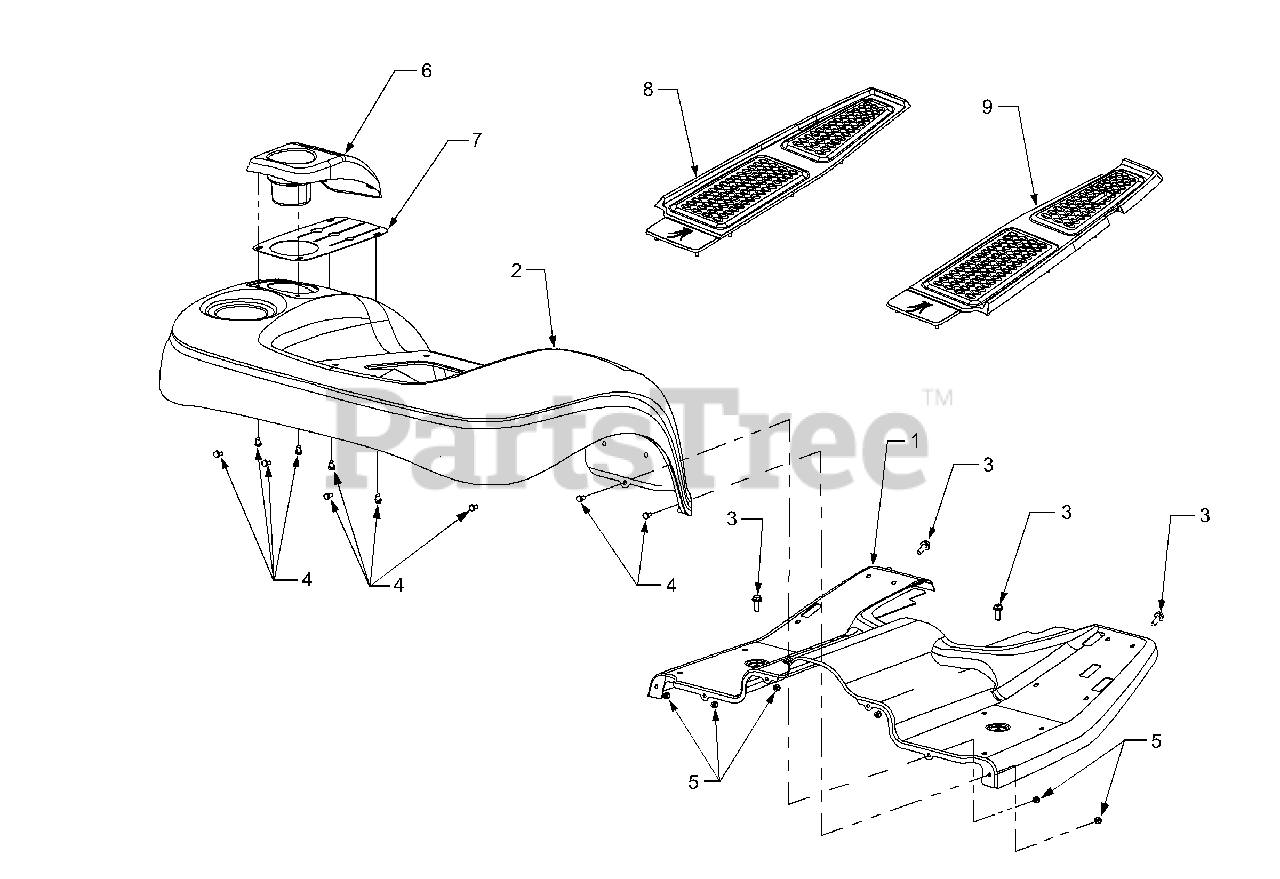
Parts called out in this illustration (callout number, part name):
1	Running Board
2	Fender
3	Screw, Hex Wash. Hd. Tapp 5/16-18 x 1.0
4	Screw, Hex Cap, 1/4-20 x .5 GR5
5	Nut, Hex Lock, 1/4-20
6	Cover, Lift Lever
7	Flap, Lift Lever
8	Pad. Floor LH.
9	Pad. Floor RH
